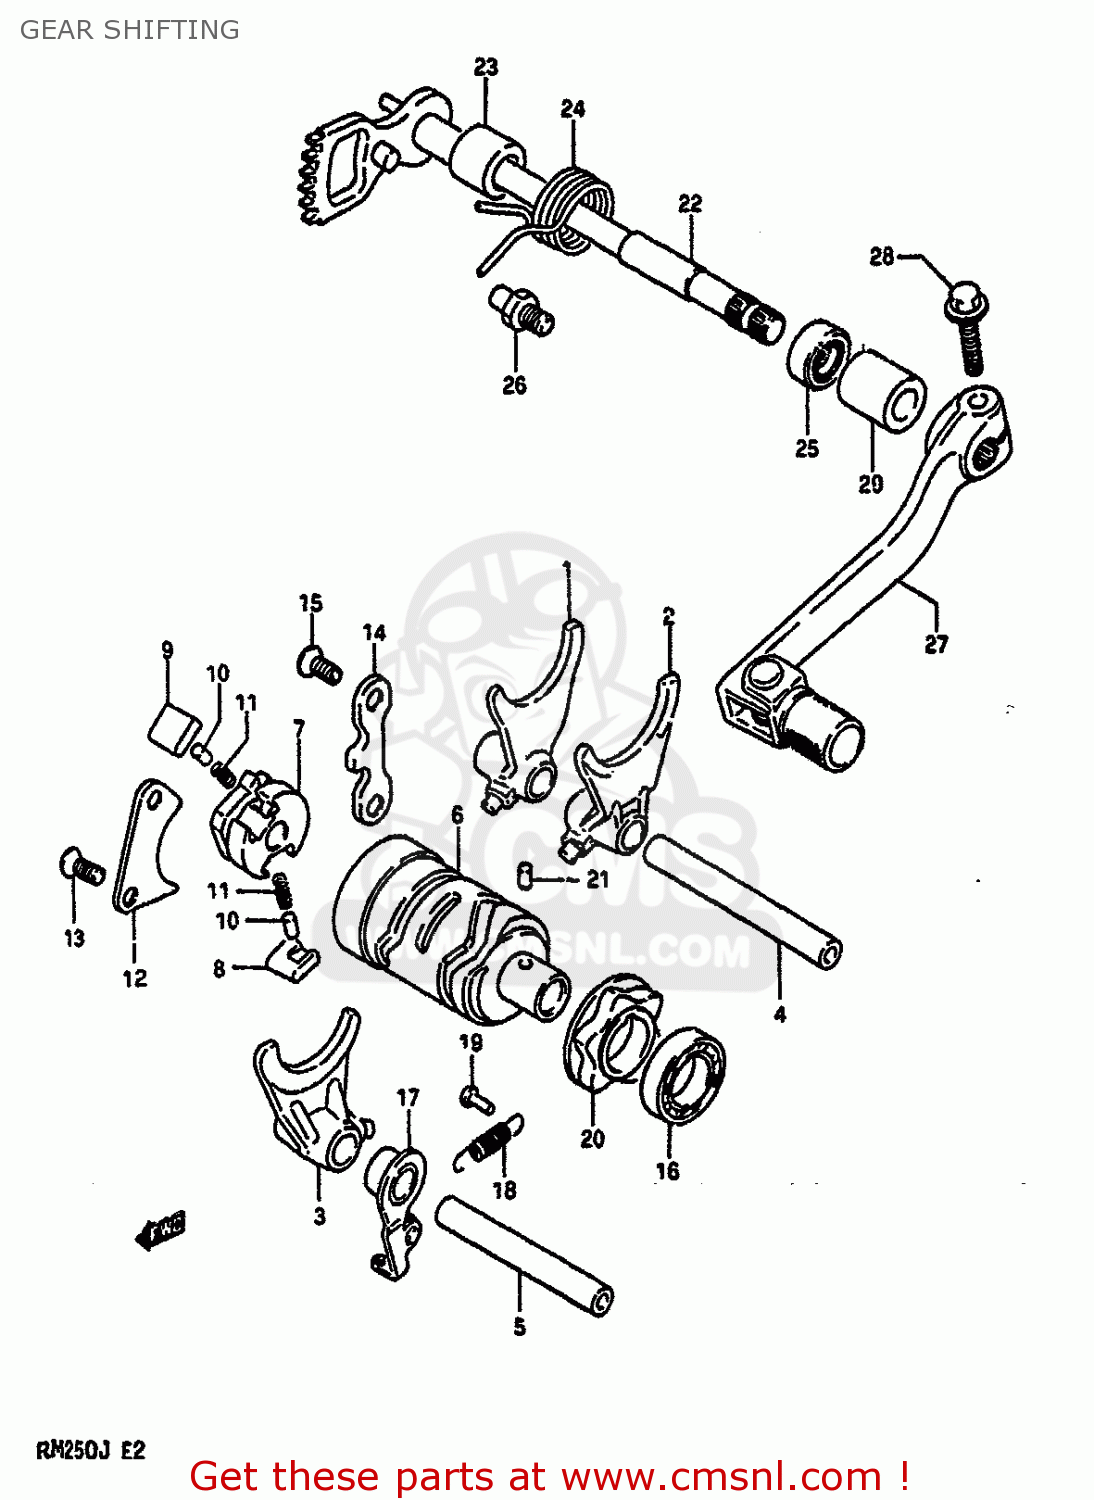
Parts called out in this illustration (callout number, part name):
1	FORK,GEAR SHIFT NO.1
2	FORK,GEAR SHIFT NO.2
3	FORK,GEAR SHIFT NO.3
4	SHAFT,GEAR SHIFT FORK
5	SHAFT,GEAR SHIFT FORK NO.2
6	CAM,GEAR SHIFT
7	GEAR,GEARSHIFT CAM DRIVE
8	PAWL,GEAR SHIFT NO.1
9	PAWL,GEAR SHIFT NO.2
10	PIN(5X8)
11	SPRING
12	LIFTER,GEAR SHIFT PAWL
13	SCREW
14	GUIDE,GEAR SHIFT CAM
15	SCREW
16	BEARING
17	STOPPER,GEAR SHIFTING CAM
18	SPRING
19	RIVET
20	PLATE,GEAR SHIFT CAM STOPPER
21	PIN
22	SHAFT COMP,GEAR SHIFTING
23	SPACER(12X20X15.3)
24	SPRING
25	OIL SEAL
26	STOPPER,GEAR SHIFT CAM
27	LEVER ASSY,GEAR SHIFT
28	BOLT
29	CUSHION 12X20X20
